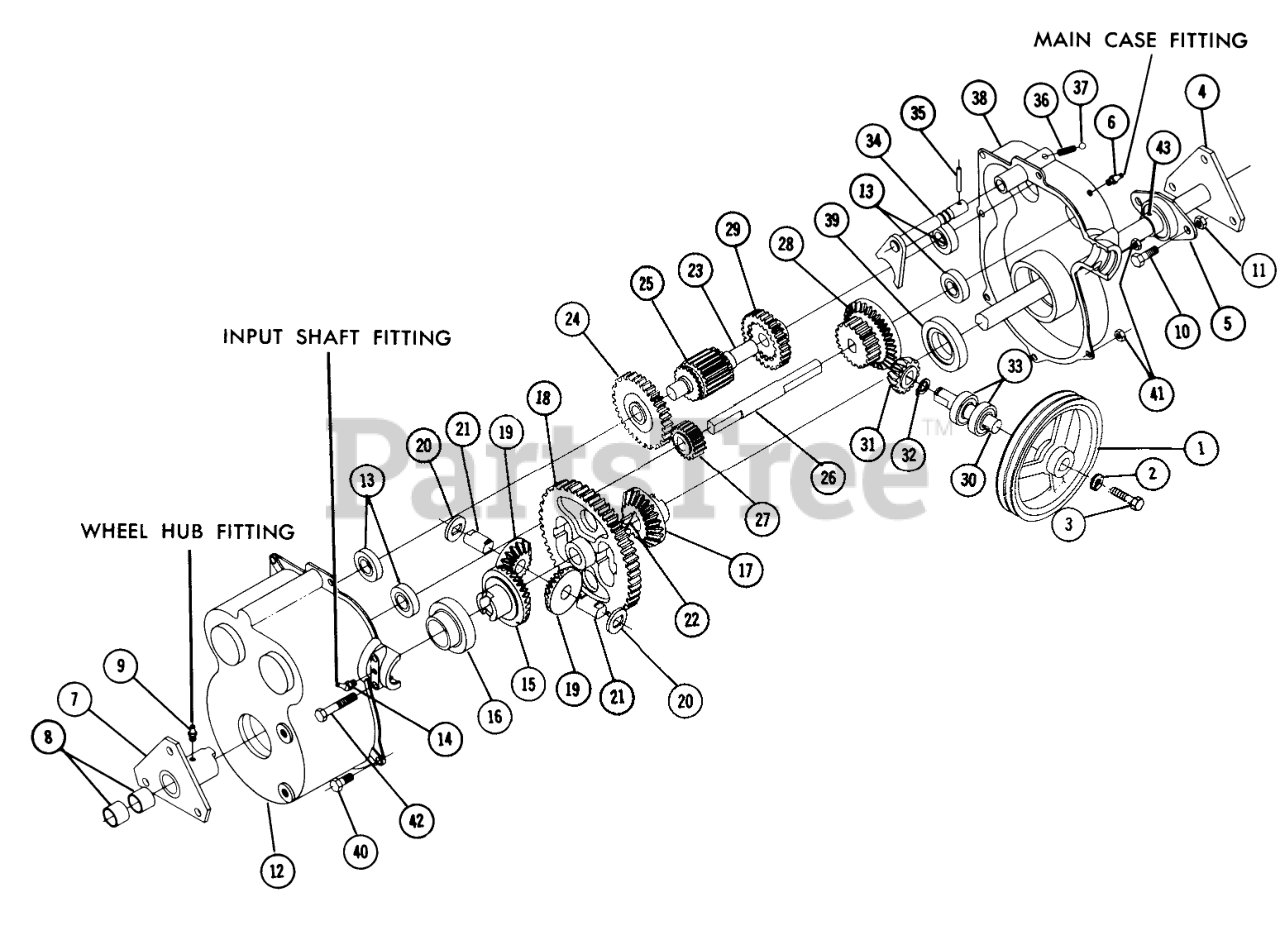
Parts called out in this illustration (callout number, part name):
2	Washer
3	Bolt, 5/16-18 x 5/8
5	Assembly Flanged Ball Bearing
8	BUSHING-BRONZE
10	Bolt Hex 3/8-16 x 5/8
22	WOODRUFF KEY
32	SNAP RING- 5/8 EXT
35	PIN-SPIROL
37	BALL-DETENT
40	Bolt, 5/16-18 X 7/8
41	Nut-5/16-18 Keps
42	Bolt Hex 5/6-18 X 2-1/2
43	Spirol Pin
